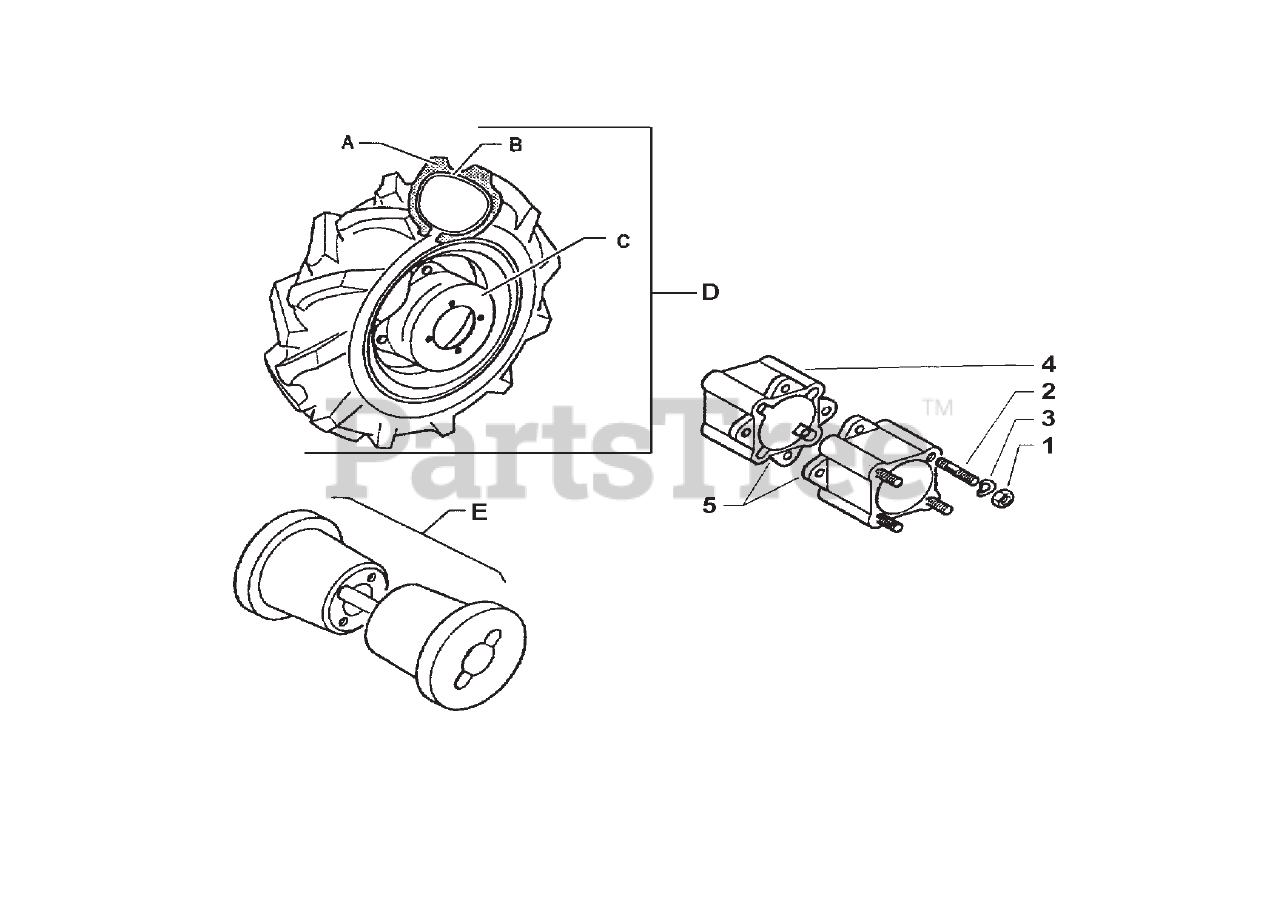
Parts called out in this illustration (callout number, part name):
1	NUT, M10
2	STUD, M10X46X24X16
3	WASHER, M10.5
5	PAIR WHEEL EXTENSIONS COMPLETE
A	TIRE 4.00 - 10"
A	TIRE 5.00 - 10"
A	TIRE 5.00 - 12"
A	TIRE 22 X 6.50 - 12"
B	TUBE 4.00 - 10"
B	TUBE 5.00 - 10"
B	TUBE 5.00 - 12"
B	TUBE 6.50 - 12"
C	RIM 4.00 - 10" & 5.00 - 10"
C	RIM 5.00 - 12" & 6.50 - 12"
D	PAIR HEELS COMPLETE - 18 X 4.00 - 10"
D	PAIR WHEELS COMPLETE - 19 X 5.00 - 10"
D	PAIR WHEELS COMPLETE - 22 X 6.50 - 12"
D	PAIR WHEELS COMPLETE - 22 X 5.00 - 12"
E	PAIR WHEEL WEIGHTS 66 LBS - 4.0-10 & 5.0-10
E	PAIR WHEEL WEIGHTS 150 LBS - 5.00-12 & 6.00-12
